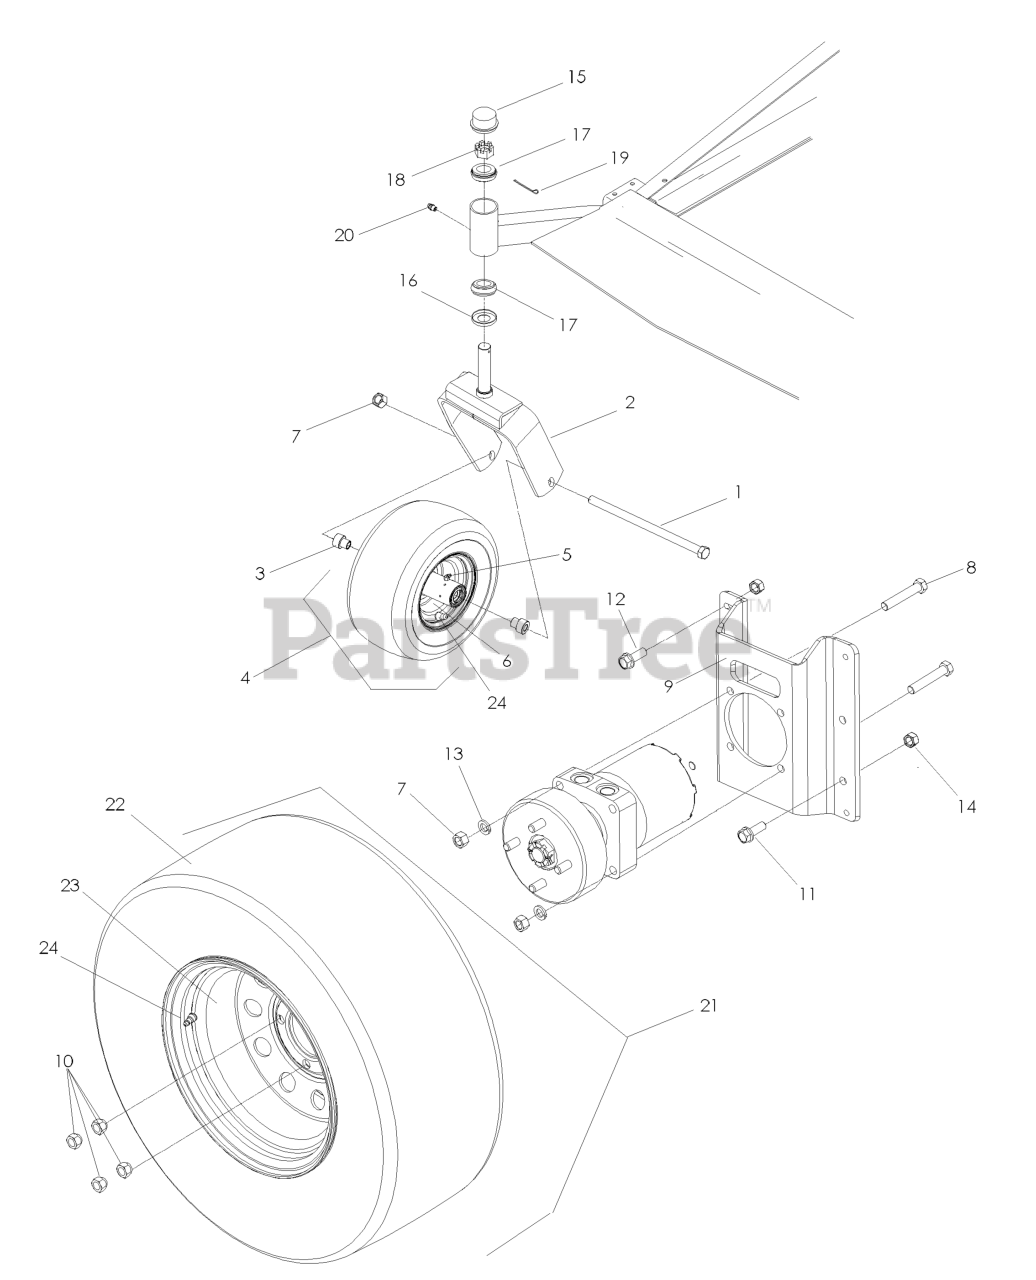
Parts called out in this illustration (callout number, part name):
1	HEX SCREW 1/2-13 X 9.5 GR5
2	CASTOR YOKE ORANGE
3	AXLE SPACER
4	FRONT TIRE ASSY
5	ZERK
7	NUT 1/2-13 HEX NYLOC ZD
8	HEX SCREW 1/2-13 X 2.5" GR 5
9	MOUNT, WHEEL-MOTOR, BLACK
10	LUG NUT 1/2F
11	HCS 1/2C X 1 1/4 SERRATED HEAD
12	HCS 3/8C X 1 1/4 GR5
13	WASHER 3/8 FLAT
14	NUT 3/8-16 NYLOC
15	GREASE CAP
17	TAPERED ROLLER BRG
18	NUT 1"C HEX SLOTTED
19	COTTER PIN 1/8 X 2
20	ZERK
21	TIRE/WHEEL ASSY 26 X 12-12
22	TIRE, 26-12 X 12
23	12"RIM 2.5" NEG OFFSET 8.5" W
24	VALVE STEM TR-412
